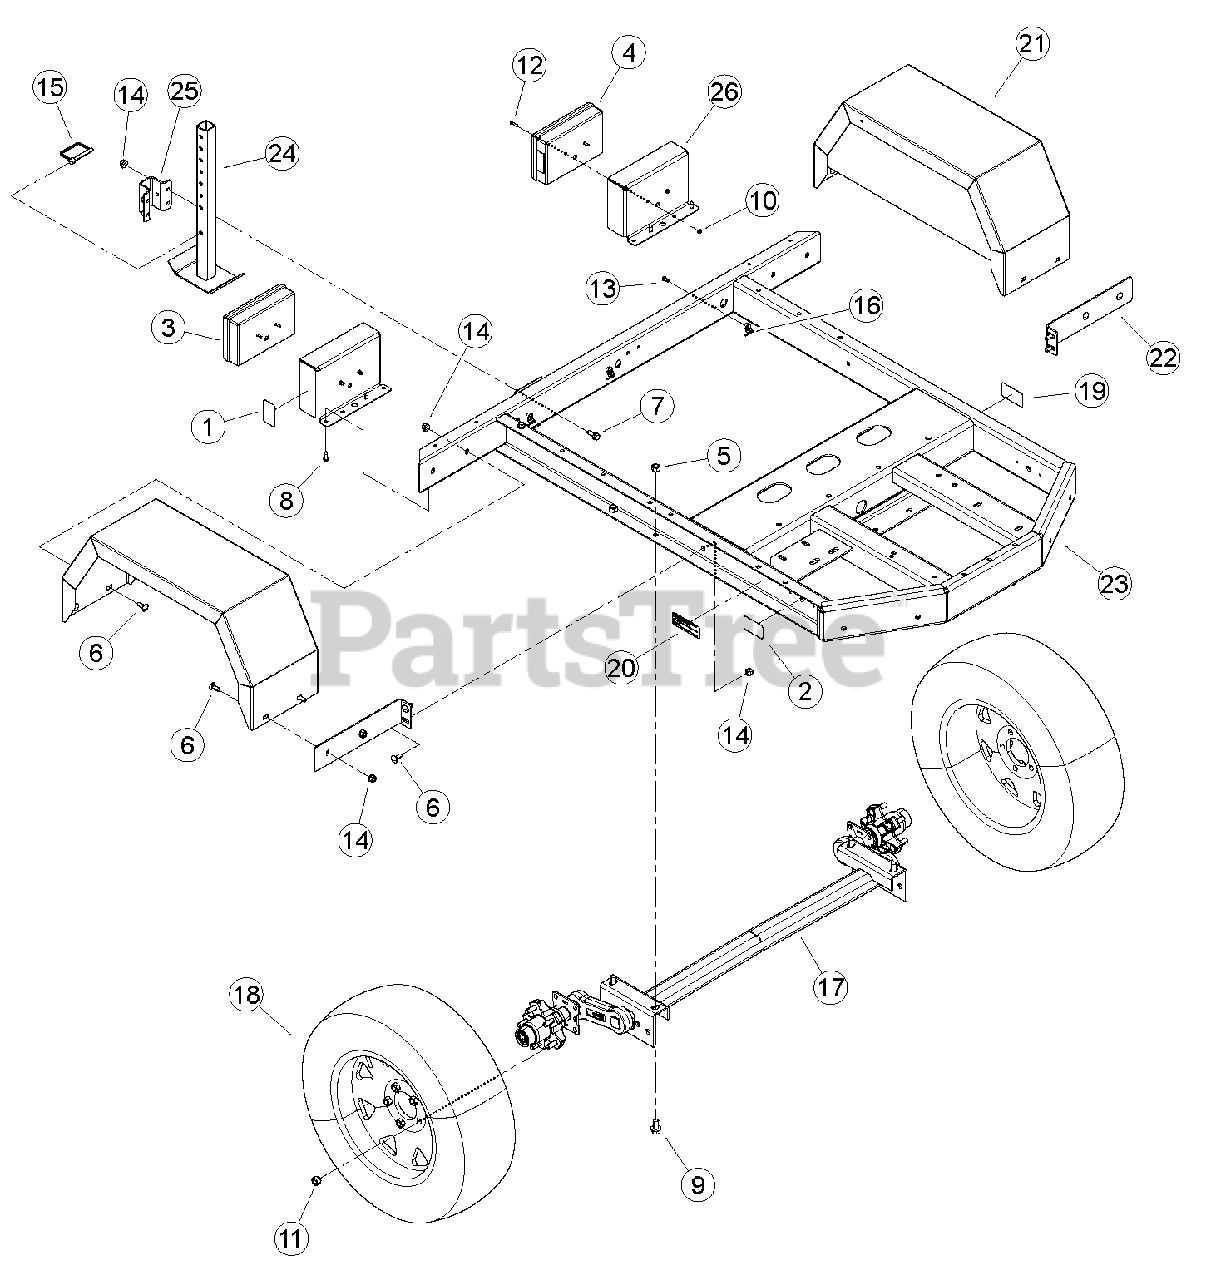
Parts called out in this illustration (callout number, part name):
1	REFLECTOR, WIDE ANGLE RED
2	REFLECTOR, WIDE ANGLE AMBER
3	LIGHT, TAIL RH
4	LIGHT, TAIL LH
5	NUT, 1/2" CENTERLOCK GRB ZP
6	BOLT, 3/8 X 1" GR5 CRG NC ZP
7	BOLT, 3/8 X 1 FLANGE NC
8	SCREW, 11/32 X 7/8 HWH AB THREAD ZP
9	BOLT, 1/2-13 1.00 GR5 FLANGE NC
10	NUT, 10/24 NYLOCK TYPE NM ZP
11	NUT, 1/2-20 WHEEL
12	BOLT, 10-24 X 3/4" HHCS GR8 PLAIN
13	RIVET, AL BLIND 1/4 X 3/4 DOME HEAD
14	NUT, 3/8-16 NYLOCK FLANGE
15	PIN, 3/8 X 2-3/4" SNAP
16	CLAMP, CABLE MOUNT
17	AXLE, TORSION 1800
18	ASSEMBLY, TIRE AND WHEEL 14 IN
19	DECAL, P205/75R14 LOAD RATING
20	DECAL, EPA EVAP
21	WELDMENT, 6" CHIPPER FENDER
22	BRACKET, 6" FENDER
23	WELDMENT, 6" CHIPPER TRAILER
24	WELDMENT, REAR STABILIZER
25	GUIDE, TRAILER SUPPORT
26	BRACKET, TAIL LIGHT
